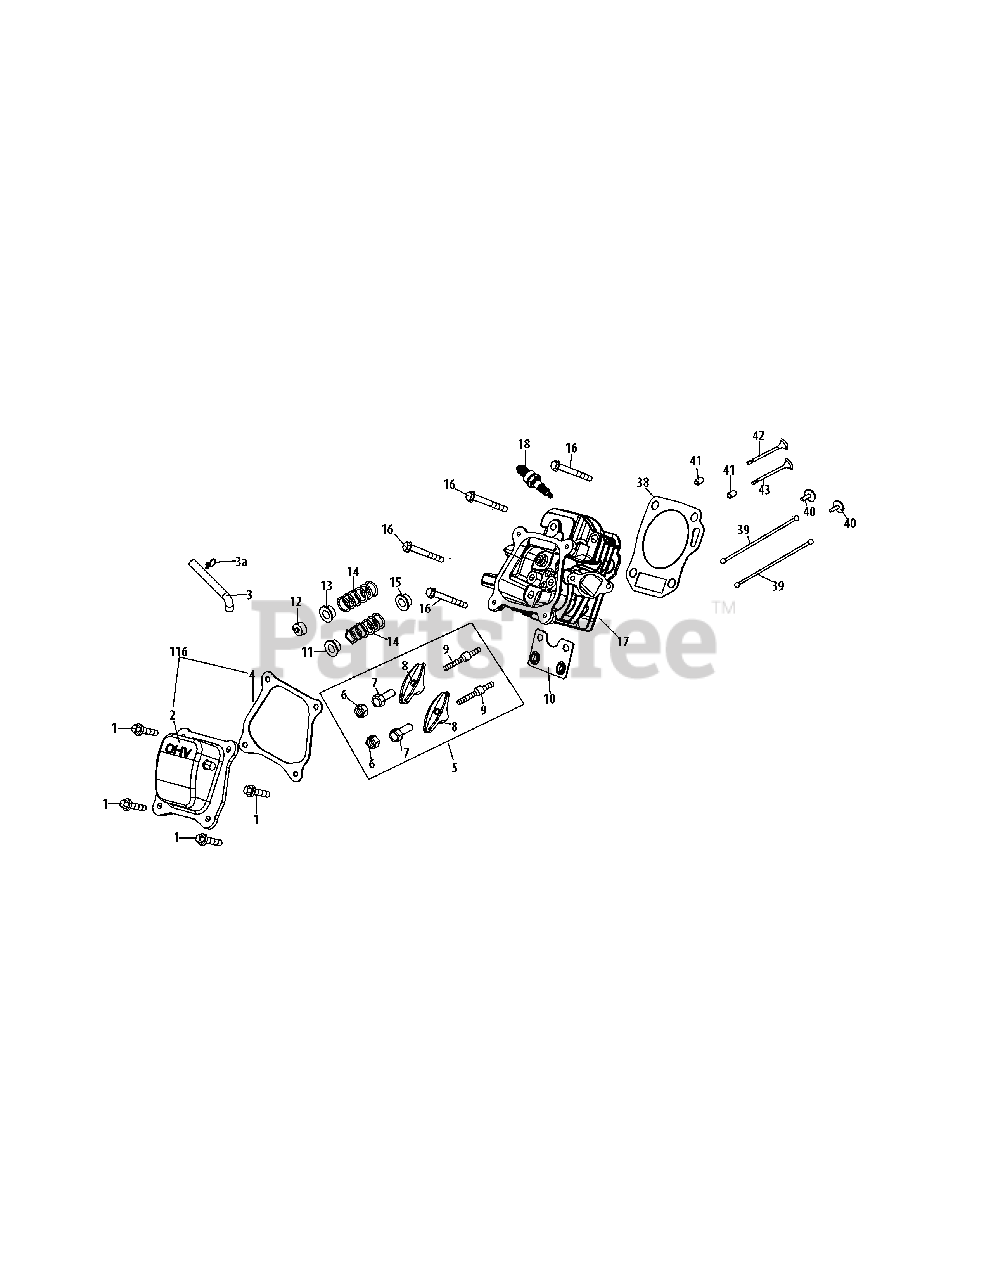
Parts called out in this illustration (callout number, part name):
1	Bolt M6×16
2	Valve Cover
3	Breather Hose Assembly
4	Valve Cover Gasket
5	Rocker Arm Assembly
6	Nut,Pivot Locking
7	Adjusting Nut ,Valve
8	Rocker Arm
9	Bolt, Pivot
10	Push Rod Guide
11	Retainer, Intake Valve Spring
12	Adjuster, Exhaust Valve
13	Retainer, Exhaust Valve Spring
14	Valve Spring
15	Intake Valve Seal
16	Bolt M8×55
17	Cylinder Head Assembly
18	Spark Plug/F6Rtc
38	Gasket, Cylinder Head
41	Dowel Pin, 10×16
116	Valve Cover Kit
